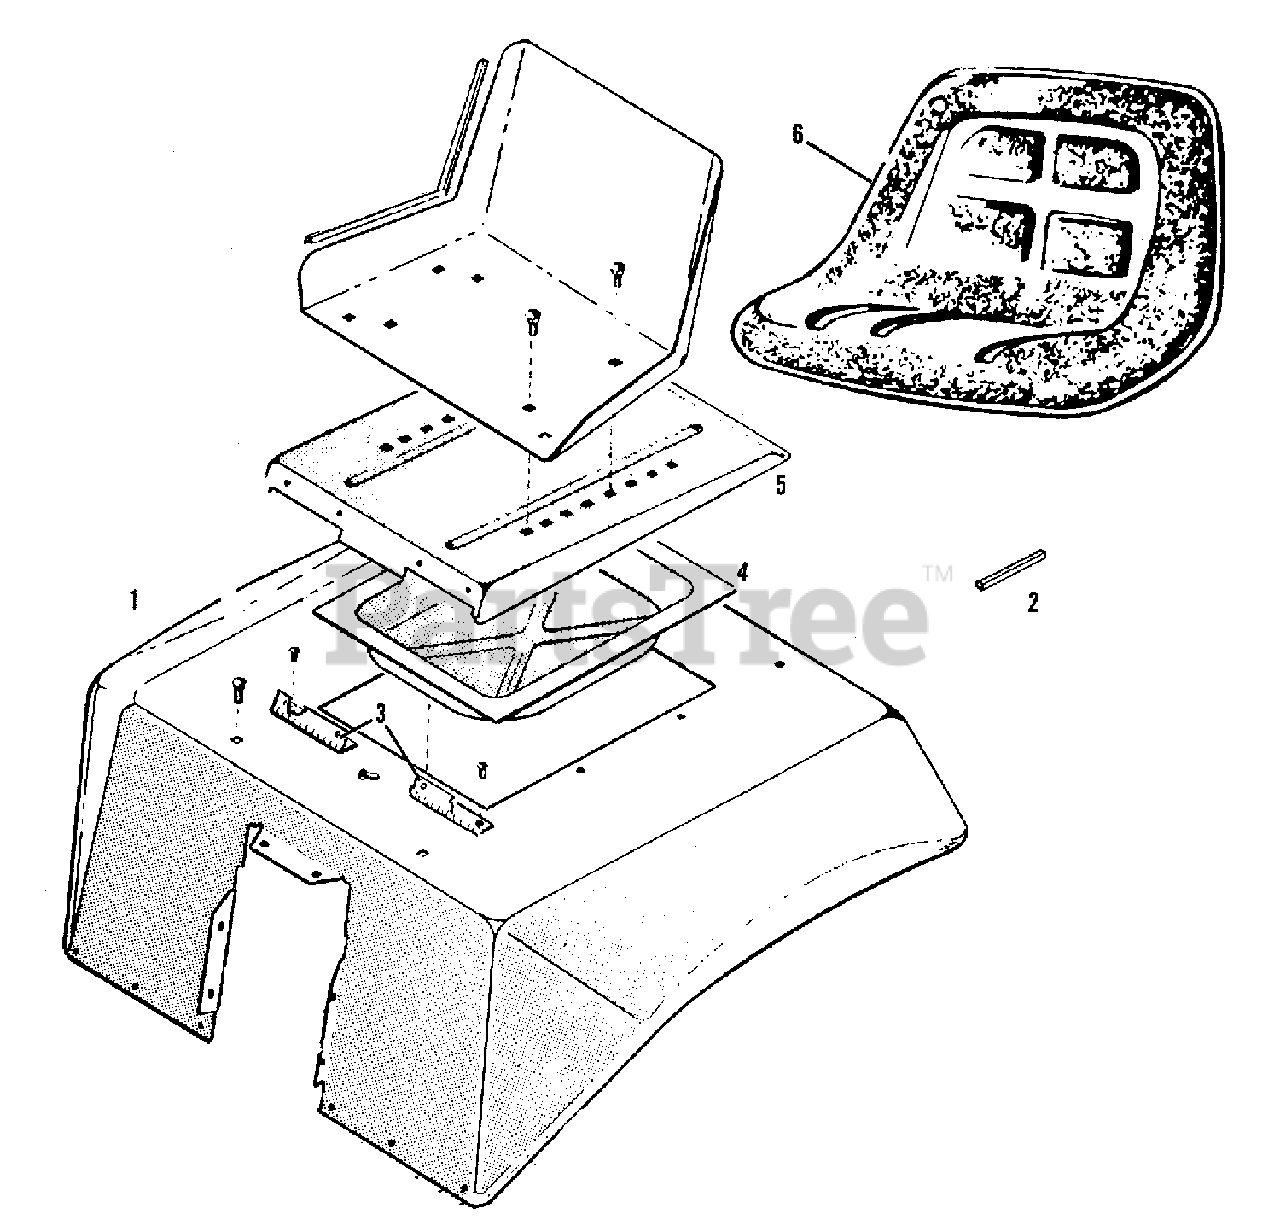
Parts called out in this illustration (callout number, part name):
1	DECK, Seat
1	CAPSCREW, 5/16NC x 5/8
1	LOCKWASHER, 5/16
1	NUT, 5/16NC
1	SCREW, 5/16NC x 1/2 Taptite
1	CASPCREW, 1/4NC x 1/2
1	LOCKWASHER, 1/4
2	TAPE Foam (Use 3 Strips-12" Long)
3	RIVET, 3/16 x .402 Pop
4	TRAY, Tool
5	SUPPORT, Seat
6	SEAT, Standard
6	CAPSCREW, 3/8NC x 1/2
6	WASHER, 3/8
6	CAPSCREW, 5/16NC x 1/2
6	WASHER, 5/16
